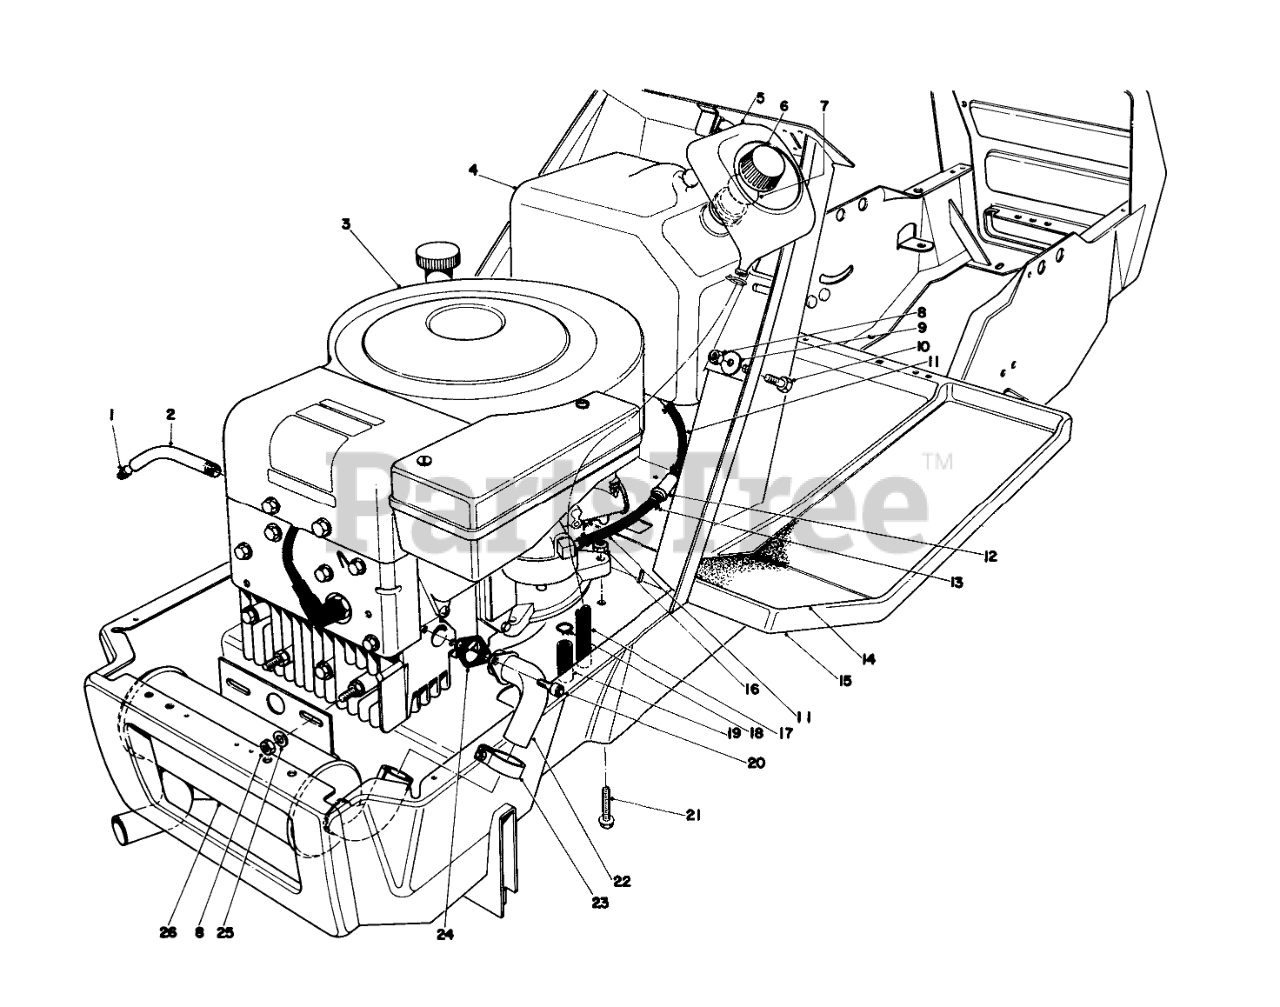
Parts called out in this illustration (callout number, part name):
1	PLUG-PIPE, SQH
2	OIL DRAIN TUBE
3	Engine
4	Gas Tank (Incl. Ref. #5)
5	Funnel Overflow
6	Gas Cap (Incl. Ref. #7)
7	Gasket Gas Cap
8	NUT-LOCK, CONE
9	WASHER
10	SCREW-HH
11	Hose Gas
12	144 Gasket
13	Clamp
14	LH FOOT TREAD
15	Frame
16	NUT-LOCK, CONE
17	Hose Funnel
18	HOSE CLAMP
19	Hose Carburetor Drain
20	SCREW-HSH
21	SCREW-HH
22	Exhaust Pipe
23	MUFFLER CLAMP
24	Gasket Exhaust
25	WASHER-PLAIN
26	MUFFLER
